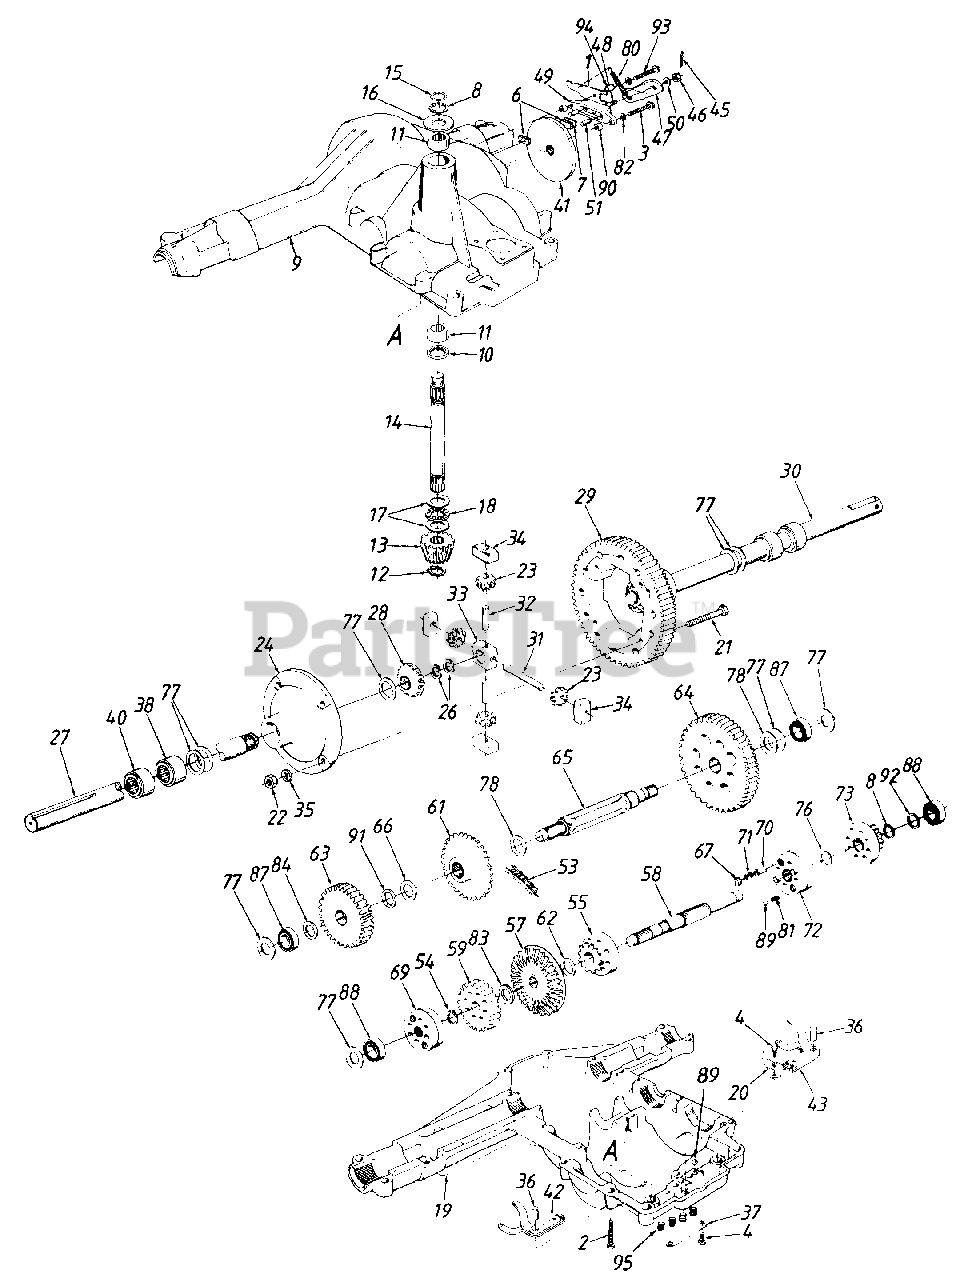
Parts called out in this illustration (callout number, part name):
1	Brake Return Bracket
2	Hex Bolt 1/4-20 x 1.25" Lg.
3	Hex Bolt 1/4-20 x 1.5" Lg. (Gr. 5)
4	Hex Wash. Hd. Tap Scr. 1/4-20 x .5" Lg.
6	Brake Puck
7	Puck Plate
8	Retainer Ring
9	Upper Housing
11	Needle Brg. 5/8" I.D. x 7/8" O.D.
12	Snap Ring
13	Input Pinion 15T
16	Thrust Washer 5/8" I.D.
17	Thrust Washer
18	Thrust Bearing
19	Lower Housing
21	Hex Bolt 3/8-24 x 2.0" Lg.
22	Hex L-Nut 3/8-24 Thd. (Gr. 5)
23	Differential Gear 10T
24	Differential Housing Cover Ass'y.
26	Retainer Ring
28	Differential Gear 14T
29	Differential Bull Gear 60T
32	Cross Shaft - Special
33	Differential Pinion Block
34	Differential Thrust Block
35	Spr. Wash. .39" I.D. x .62" O.D.
37	Spring Plate
38	Axle Bearing Ass'y.
40	Axle Bearing Ass'y.
41	Brake Disc
42	Shift Arm Ass'y. - R.H.
43	Shift Arm Ass'y. - L.H.
45	Cotter Pin 3/32" Dia.
46	Castle Nut 5/16-24 Thd.
47	Brake Actuating Arm
48	Sq. Hd. Bolt 5/16-24 Thd.
50	Fl-Wash. 11/32" I.D. x 7/8" O.D.
51	Brake Actuating Pin
53	#420 Chain 1/2 Pitch x 28 Links
54	Retainer Ring
55	Reverse Sprocket Ass'y.
57	Bevel Gear 47T
58	Drive Shaft
59	Spur Gear Ass'y.
61	Sprocket 22T
62	Fl-Wash. .81" I.D. x 1.18" O.D.
63	Spur Gear 31T
64	Spur Gear 45T
65	Output Shaft 9T
67	Shift Spring Plug
69	Forward Shift Collar
70	Drive Pin
71	Drive Spring
72	Creeper Shift Collar
73	Creeper Collar Plate Ass'y.
76	Fl-Wash. .65" I.D. x .97" O.D.
77	Fl-Wash. 1" I.D. x 1.56" O.D. x .010" Thk.
78	Fl-Wash. 1.0" I.D. x 1.56" O.D.
80	Ext. Spring 1.14" Lg
81	Detent Spring
82	L-Wash. 1/4" I.D.
83	Fl-Wash. 5/8" I.D. x 1.0" O.D.
84	Fl-Wash. .68" x 1.12"
87	Ball Brg. .669" I.D.
88	Ball Bearing
89	Ball Detent .25" Dia.
90	Spacer .254" I.D. x .5" O.D.
91	Fl-Wash. .69" I.D. x 1.06" O.D.
92	Fl-Wash. 5/8" I.D. x 1.0" O.D. x .020" Thk.
93	Hex Wash. Hd. Patch Bolt 1/4-20 x 2-1/4" Lg.
94	Spacer .256" I.D. x .75" O.D.
95	Detent Spring
